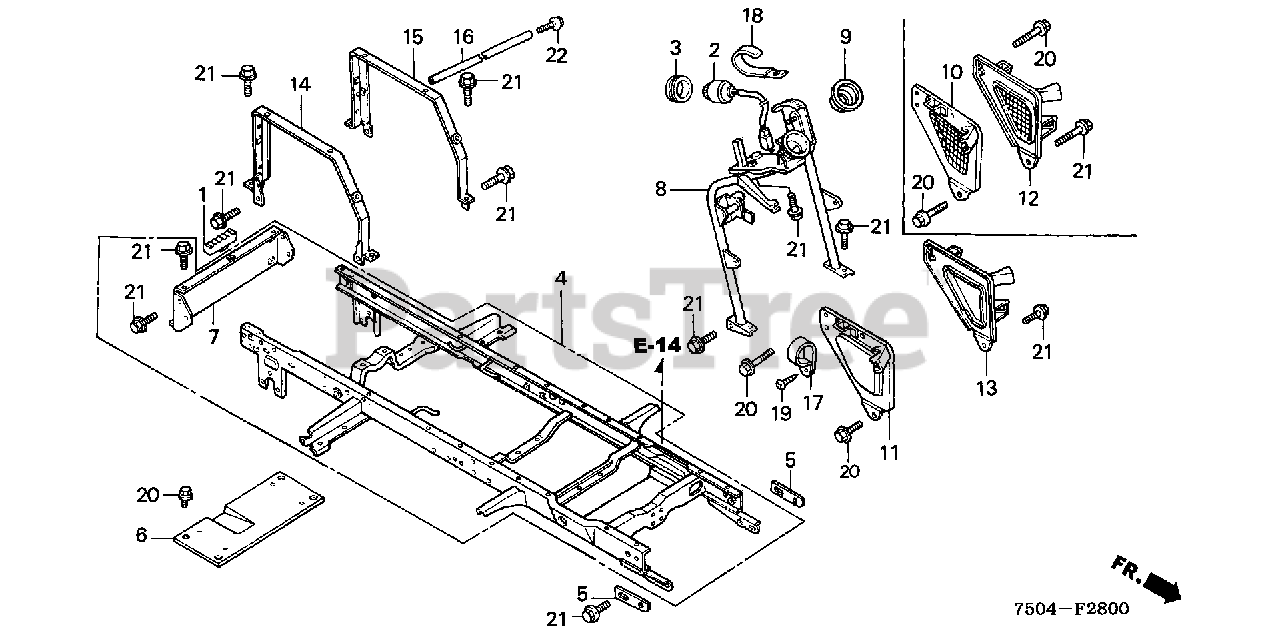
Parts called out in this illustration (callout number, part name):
1	RUBBER, TANK CUSHION
2	BUZZER, WARNING
3	GROMMET, PARKING BRAKE BUZZER
5	PLATE, HINGE ADJUSTER
6	CROSSMEMBER, FRAME
7	HITCH, TRAILER
8	COLUMN, STEERING
9	CUSHION, HOOD
10	STRIKER, R. HOOD
12	STRIKER, L. HOOD
14	FRAME, R. RR.
15	FRAME, L. RR.
16	STIFFENER, RR. FRAME
17	CLIP (14MM)
18	CLIP, WIRE HARNESS
19	SCREW, TAPPING (5X8)
20	BOLT, FLANGE (8X12)
21	BOLT, FLANGE (8X14)
22	BOLT, FLANGE (8X25)
